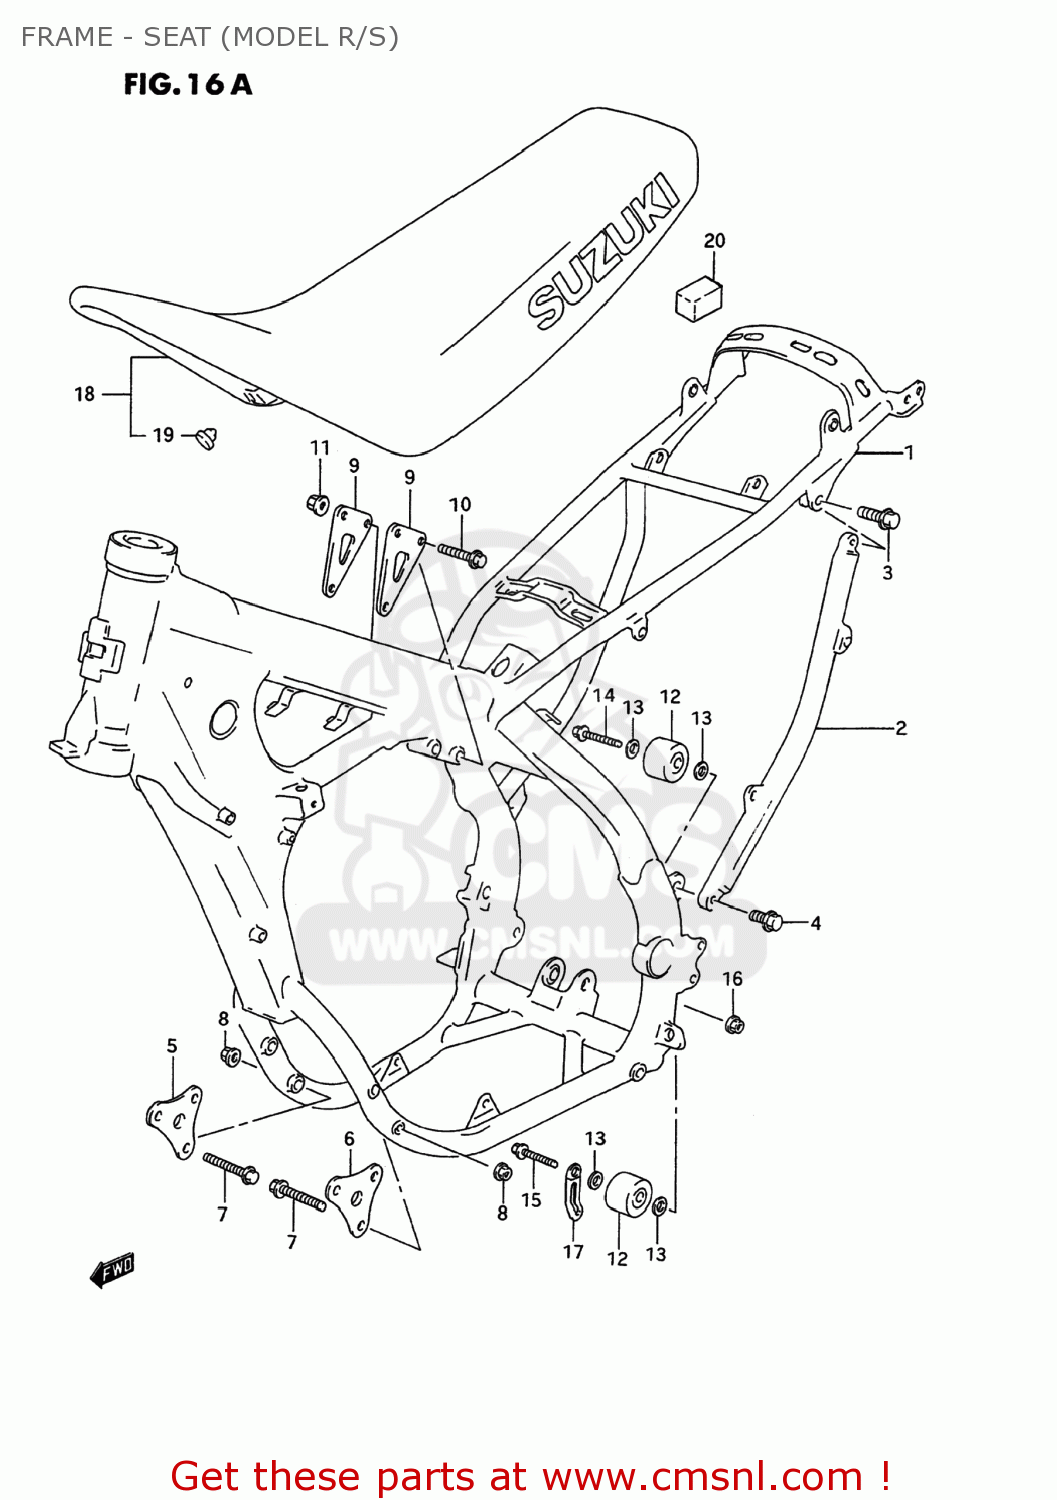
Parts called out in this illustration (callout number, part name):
1	FRAME
2	TUBE,FRAME SIDE,L
3	BOLT
4	BOLT, LOWER
5	PLATE,ENG MTG FR
6	PLATE,ENGINE MOUNTING
7	BOLT
8	NUT
9	PLATE,ENG MTG UPR
10	BOLT(8X45)
11	NUT
12	ROLLER,CHAIN
13	WASHER
14	BOLT(8X41)
15	BOLT(8X45)
16	NUT
17	CLAMP(L:120 T:1.0)
18	SEAT ASSEMBLY
19	CUSHION
20	CUSHION,SEAT
